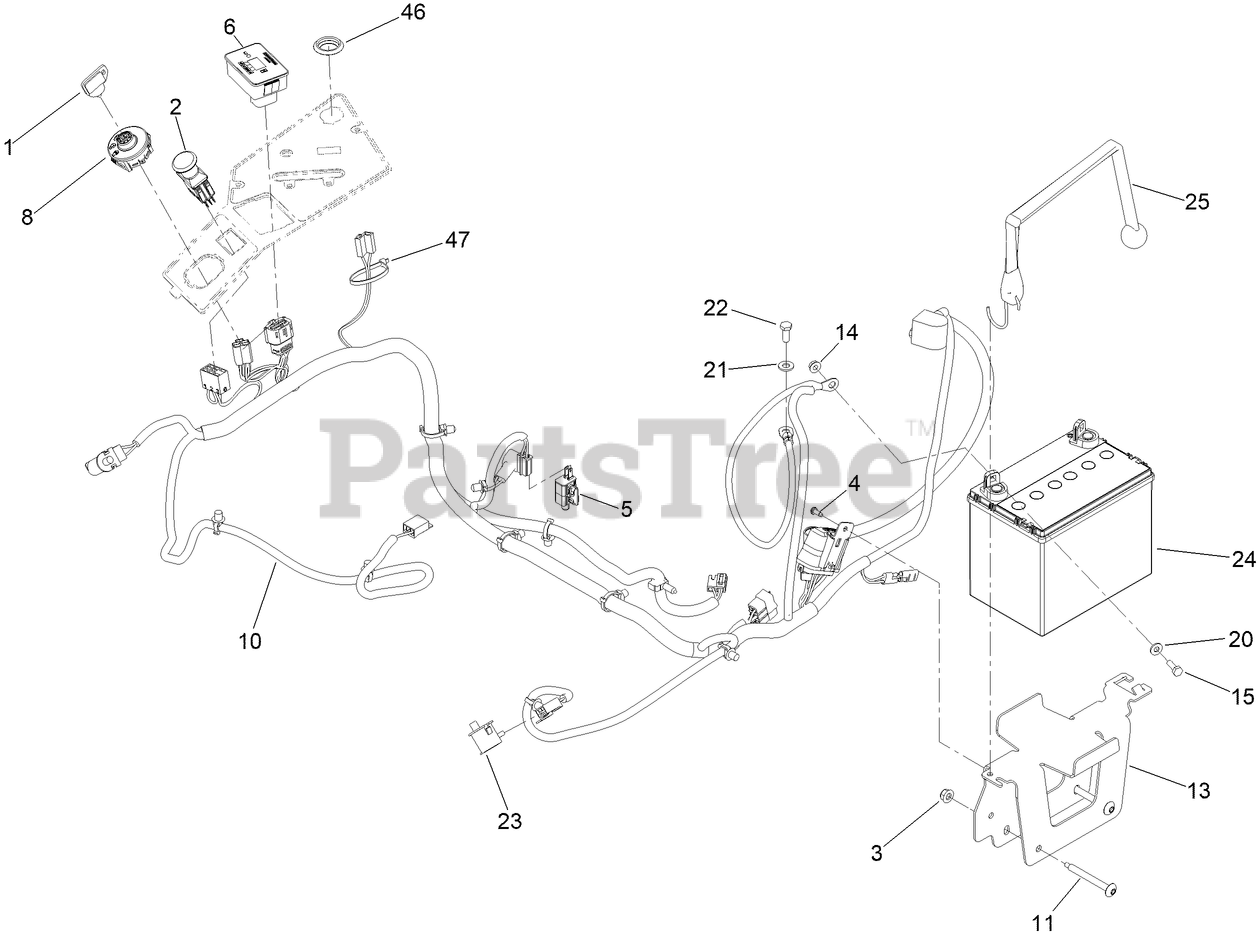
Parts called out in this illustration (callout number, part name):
1	KEY-IGNITION
2	SWITCH-PTO
3	NUT-HF, NI
4	SCREW-FORMING, THREAD
5	SWITCH
6	MODULE ASM
8	SWITCH-IGNITION
10	HARNESS-WIRE
11	SCREW-TORX
13	TRAY-BATTERY
14	NUT-HF
15	SCREW-HH
20	WASHER-FLAT
21	WASHER-PLAIN
22	SCREW-HH
23	SWITCH-BAIL
24	BATTERY
25	STRAP-BUNGEE
46	PLUG-PLASTIC
47	TIE-CABLE
